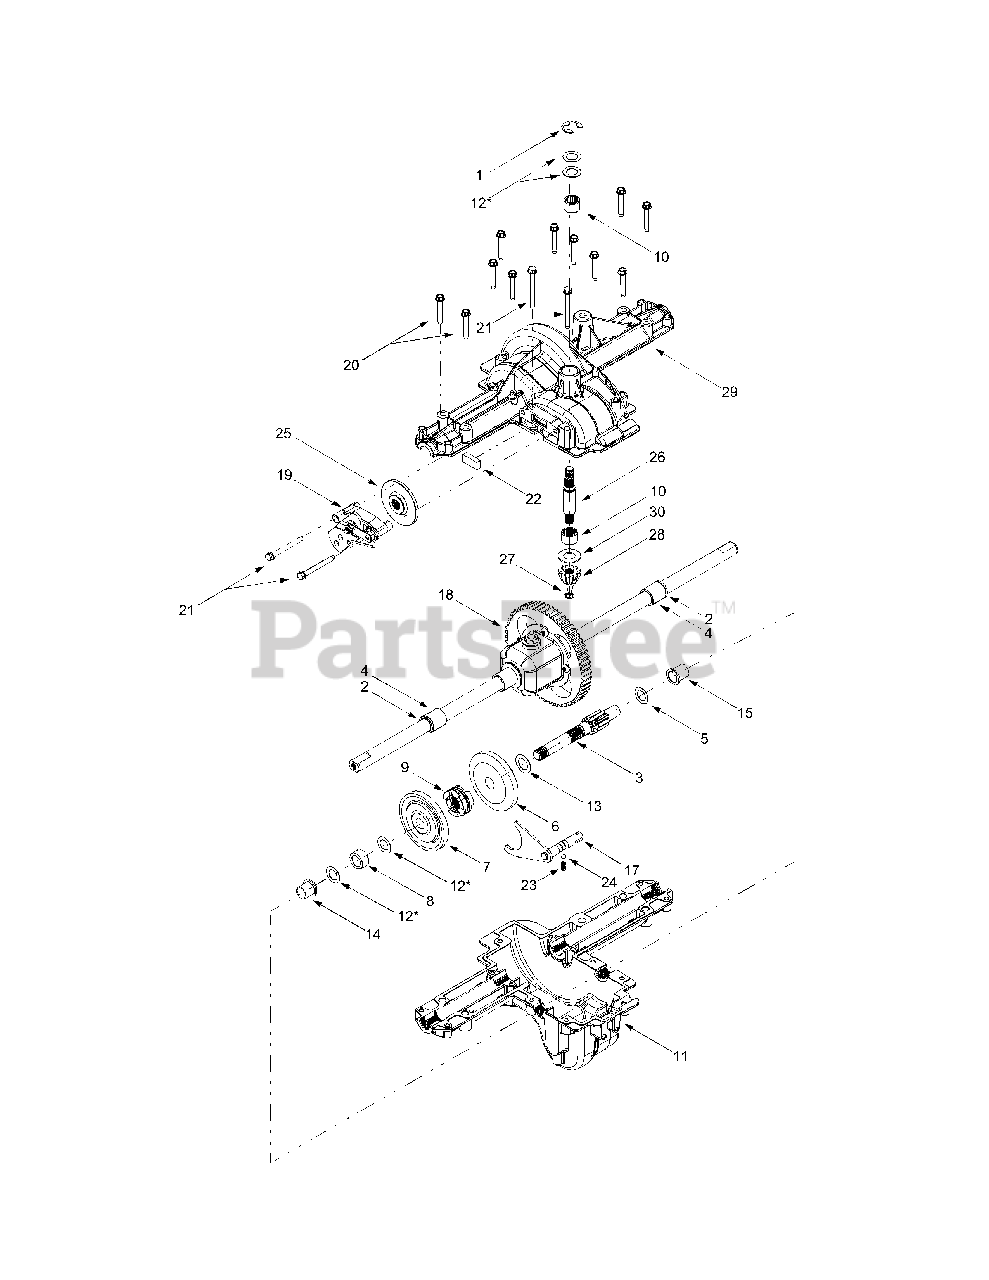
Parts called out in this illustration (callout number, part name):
1	E-ring, .75
2	Seal, .75 x 1.0 x .125
3	Drive Shaft
4	Sleeve Bearing, .75 x .1.0 x 1.0
5	Thrust Washer, 1.0 x .632 x .0
6	42-tooth Bevel Gear
7	42-tooth Bevel Gear
8	Spacer, .633 x 1.0 x .513
9	Clutch Collar
10	Needle Bearing, .625 x .813 x 495
11	Lower Housing
13	Flat Washer, .70 x 1.125 x .031
14	Flange Bearing, 5/8 x 3/4 x 3/4
15	Flange Bearing, 5/8 x 3/4 x 15/16
16	Spacer, .635 x 1.0 x .27
17	Detent Shaft Assembly
18	Differential Assembly
19	Brake Assembly
20	Self-tapping Screw, 1/4-20 x 1.625
21	Self-tapping Screw, 1/4-20 x 2.375
22	Brake Pad
23	Compression Spring
24	Detent Ball
25	Brake Disc
26	Input Shaft
27	Retaining Ring, .437
28	14-tooth Bevel Pinion
29	Upper Housing
30	Thrust Washer, .635 x 1.26 x .06
